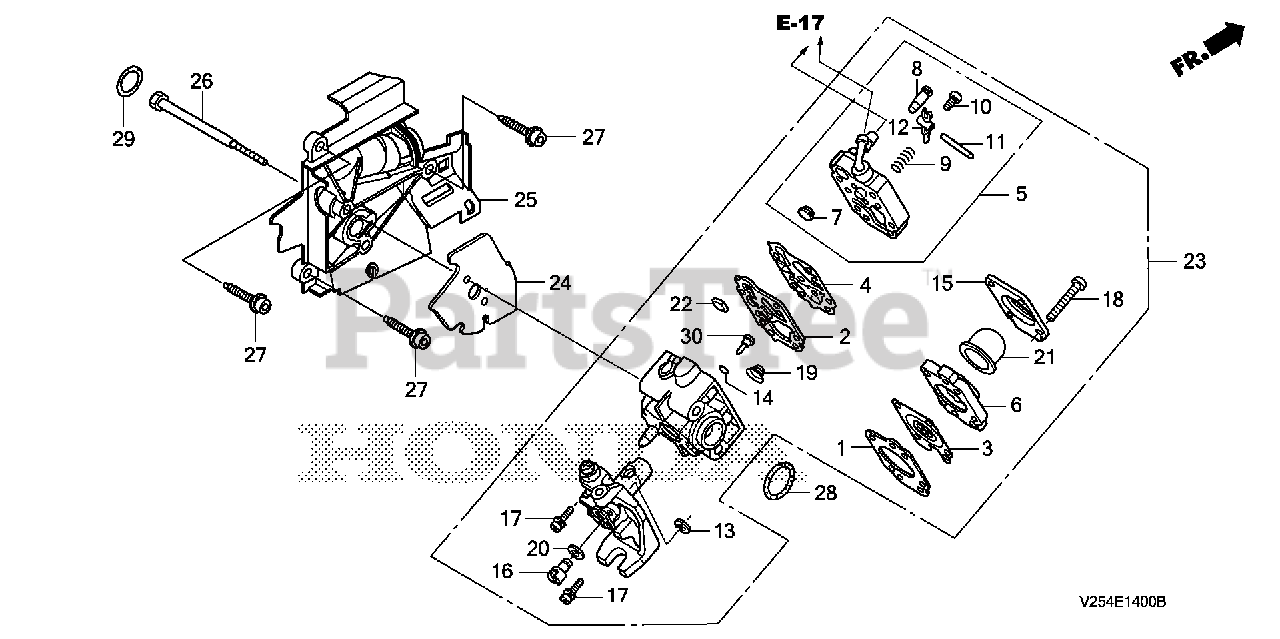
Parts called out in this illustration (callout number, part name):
1	GASKET, METERING DIAPHRAGM
2	GASKET, PUMP
3	DIAPHRAGM ASSY., METERING
4	DIAPHRAGM, PUMP
5	BODY ASSY., PUMP (CARBURETOR NO.)
6	BODY ASSY., AIR PURGE
7	SCREEN, INLET
8	VALVE, INLET NEEDLE
9	SPRING, METERING LEVER
10	SCREW, METERING LEVER PIN
11	PIN, METERING LEVER
12	LEVER, METERING
13	RING, RETAINING
15	COVER, PRIMER PUMP
17	SCREW, THROTTLE COLLAR
18	SCREW, PUMP COVER
19	SPRING, PUMP
21	PUMP, PRIMER
22	FILTER, FUEL INLET
23	CARBURETOR ASSY. (WYB 9B)
23	CARBURETOR ASSY. (WYB 6F)
24	GASKET, CARBURETOR
26	BOLT (5X53)
27	BOLT, SOCKET (5X16)
28	O-RING (14.8X2.4)
29	O-RING (12.3X2.4)
30	JET (#33)
30	JET (#32)
